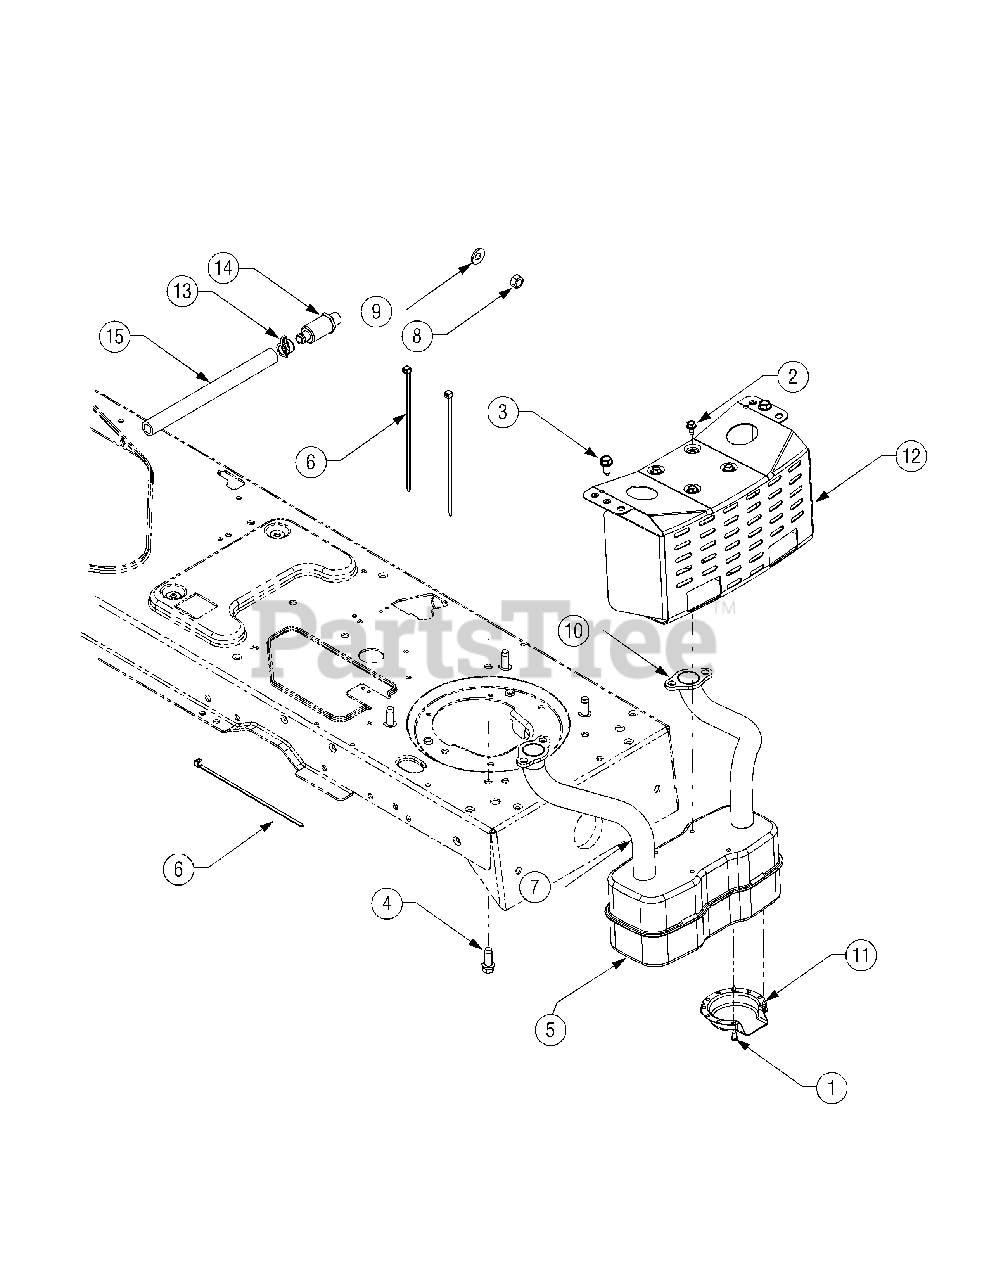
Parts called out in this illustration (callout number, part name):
1	Screw, #8-18, 0.500
2	Screw, Hex, 1/4-20, 0.500
3	Screw, Hex, 5/16-12 x.75
4	Screw, Hex, 3/8-16 x 1.25
5	Muffler, Dual Inlet
6	Cable, Tie, 3/16 x.05 x 7.4
7	Pipe, Exhaust, RH
8	Flange Lock Nut, 3/8-16
9	Flat Washer,.406 x.875 x.059
10	Pipe, Exhaust, LH
11	Deflector, Muffler
13	Cap, Oil Drain
14	Drain, Oil
15	Extension Hose, Oil Drain
